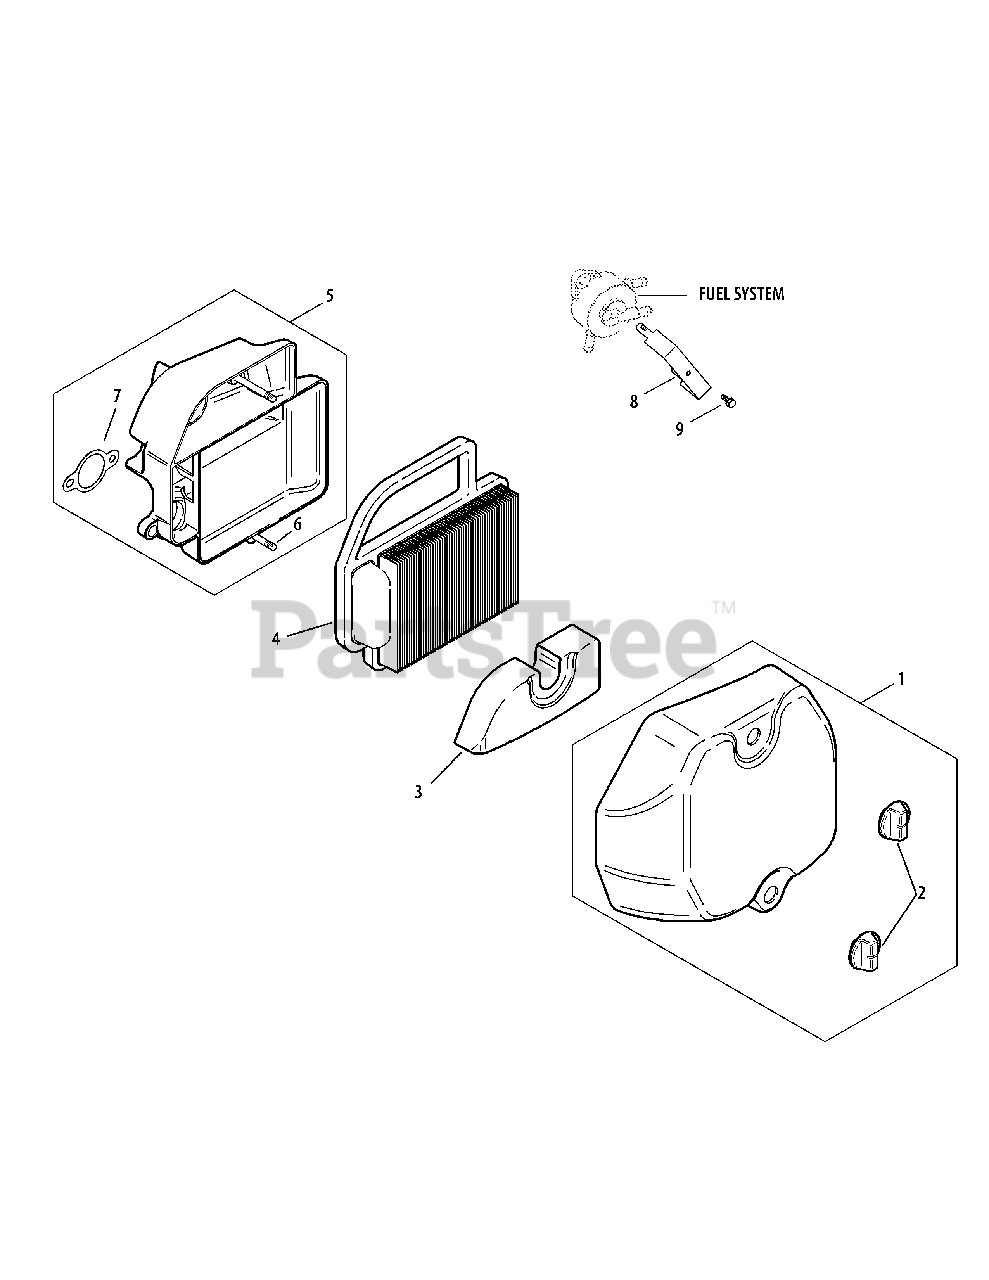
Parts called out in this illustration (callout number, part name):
1	Air Cleaner Cover Kit (Inc. 2)
3	Pre-Cleaner Element (Dry)
4	Air Cleaner & Pre-Cleaner Elements
5	Air Cleaner Base Kit (Inc. 6, 7)
6	Air Cleaner Base Stud
7	Air Cleaner Base Gasket
8	No used in this application
9	No used in this application
